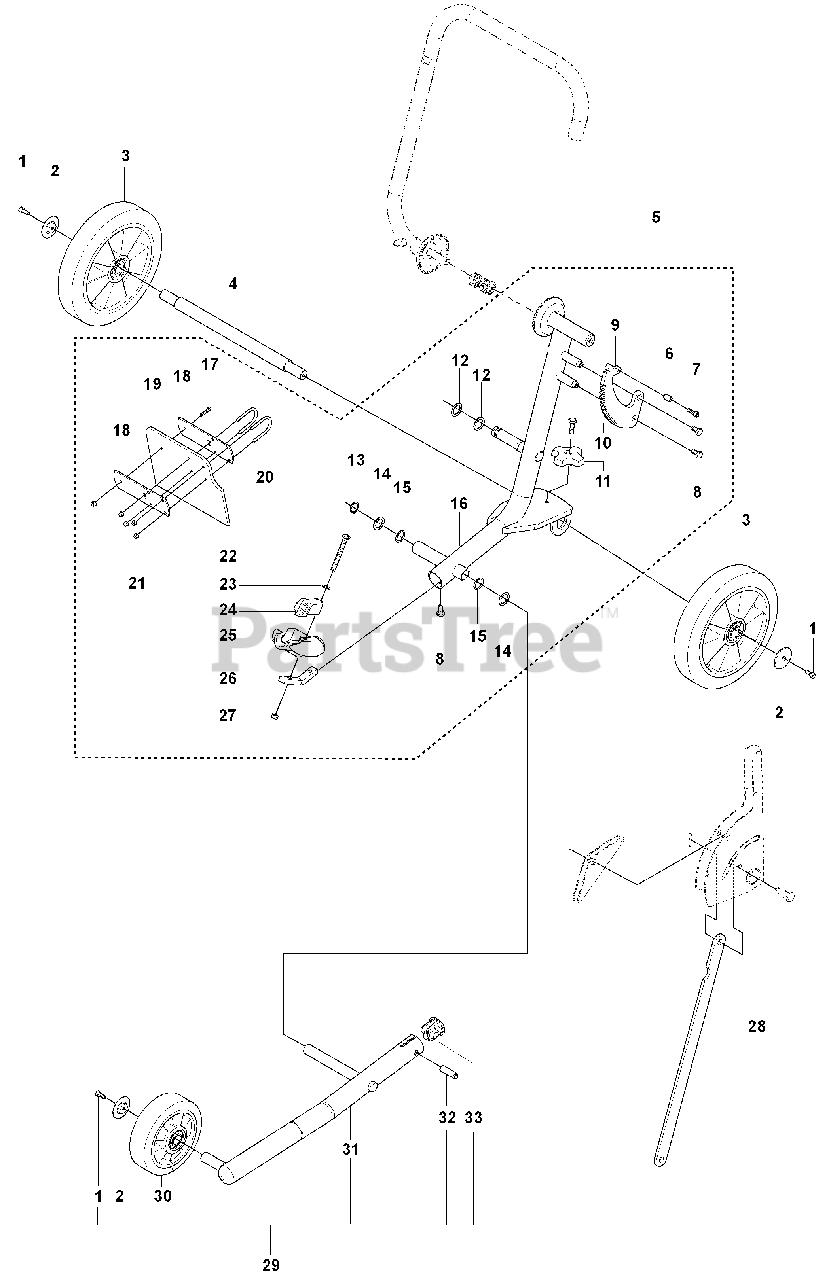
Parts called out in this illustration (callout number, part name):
3	WHEEL ASSY
5	FRAME
6	DRIVE SCREW
7	SCREW
8	SCREW
11	KNOB
13	RETAINING RING
16	FRAME TUBE
23	WASHER
24	TURNING KNOB
27	NUT
29	FRAME TUBE
32	SPRING PIN
